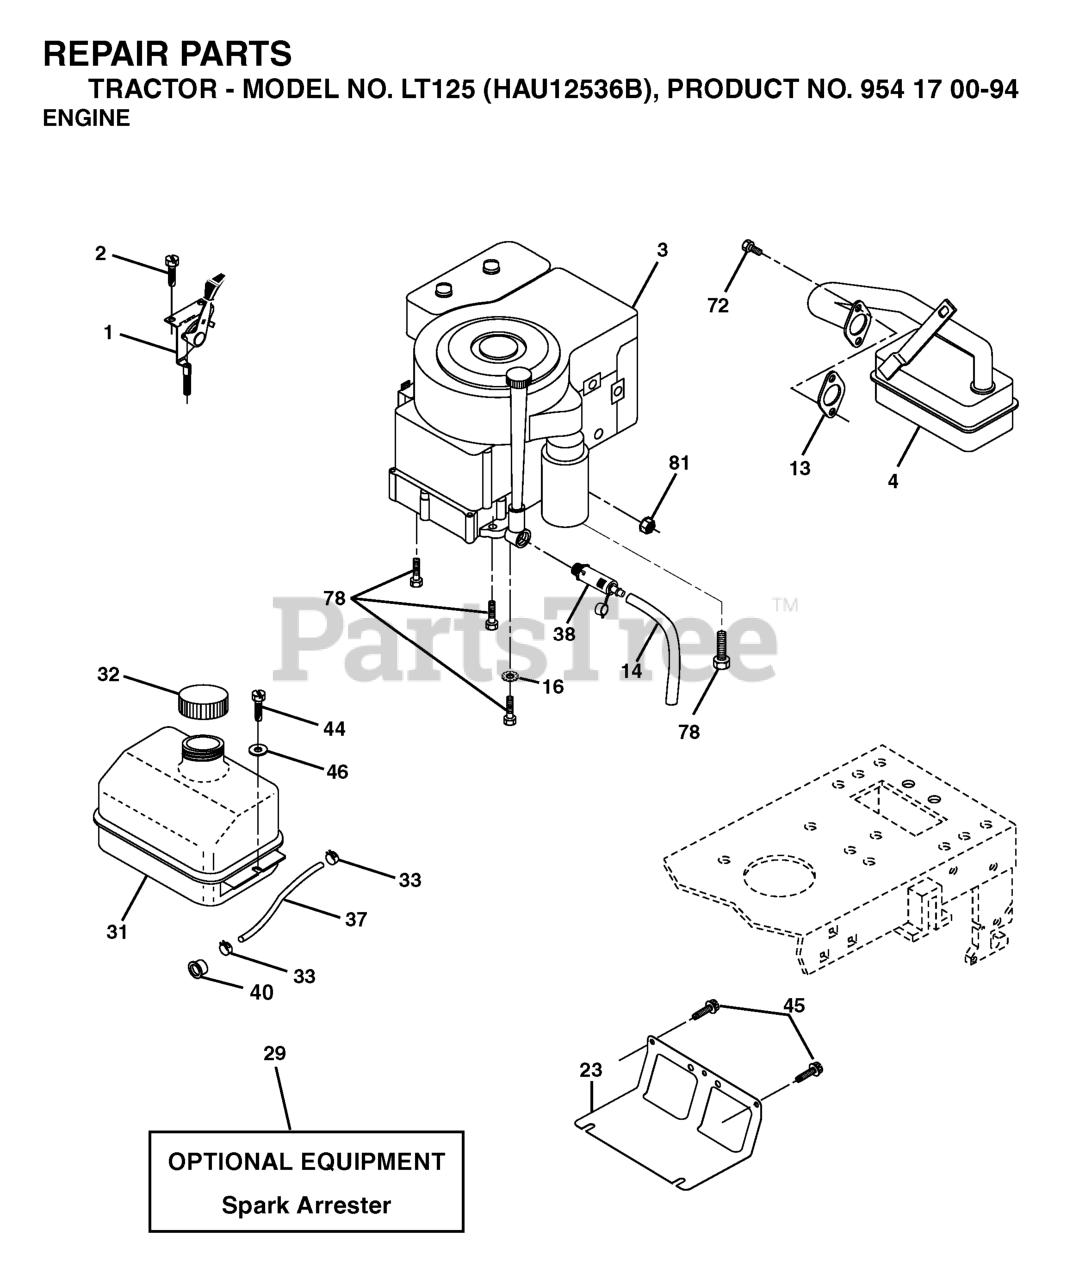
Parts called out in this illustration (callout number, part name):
1	CONTROL.THROTTLE/CHOKE.BLACK
2	SCREW
4	MUFFLER.B&S.MODEL.21.11HP.OHV
13	REPL BY 532 27 22-93
14	TUBE, DRAIN OIL ASM.
16	LOCKWASHER
23	SHIELD.BROWNING.DBR.GUARD
29	KIT.SPARK ARRESTOR 794945 B&S
31	TANK.ASM.FUEL.FRONT.W/CAP
32	FUEL CAP
33	HOSE CLAMP
37	LINE.FUEL.20
38	PLUG DRAIN OIL EASY
40	BUSHING.SNAP.NYL.BLK.
44	SCREW HEXWSHR 1/4-20X3/4
45	SCREW, 3/8-16X3/4
72	SCREW.SOCKET.HEAD.5/16-18
78	SCREW.3/8-16
81	NUT
